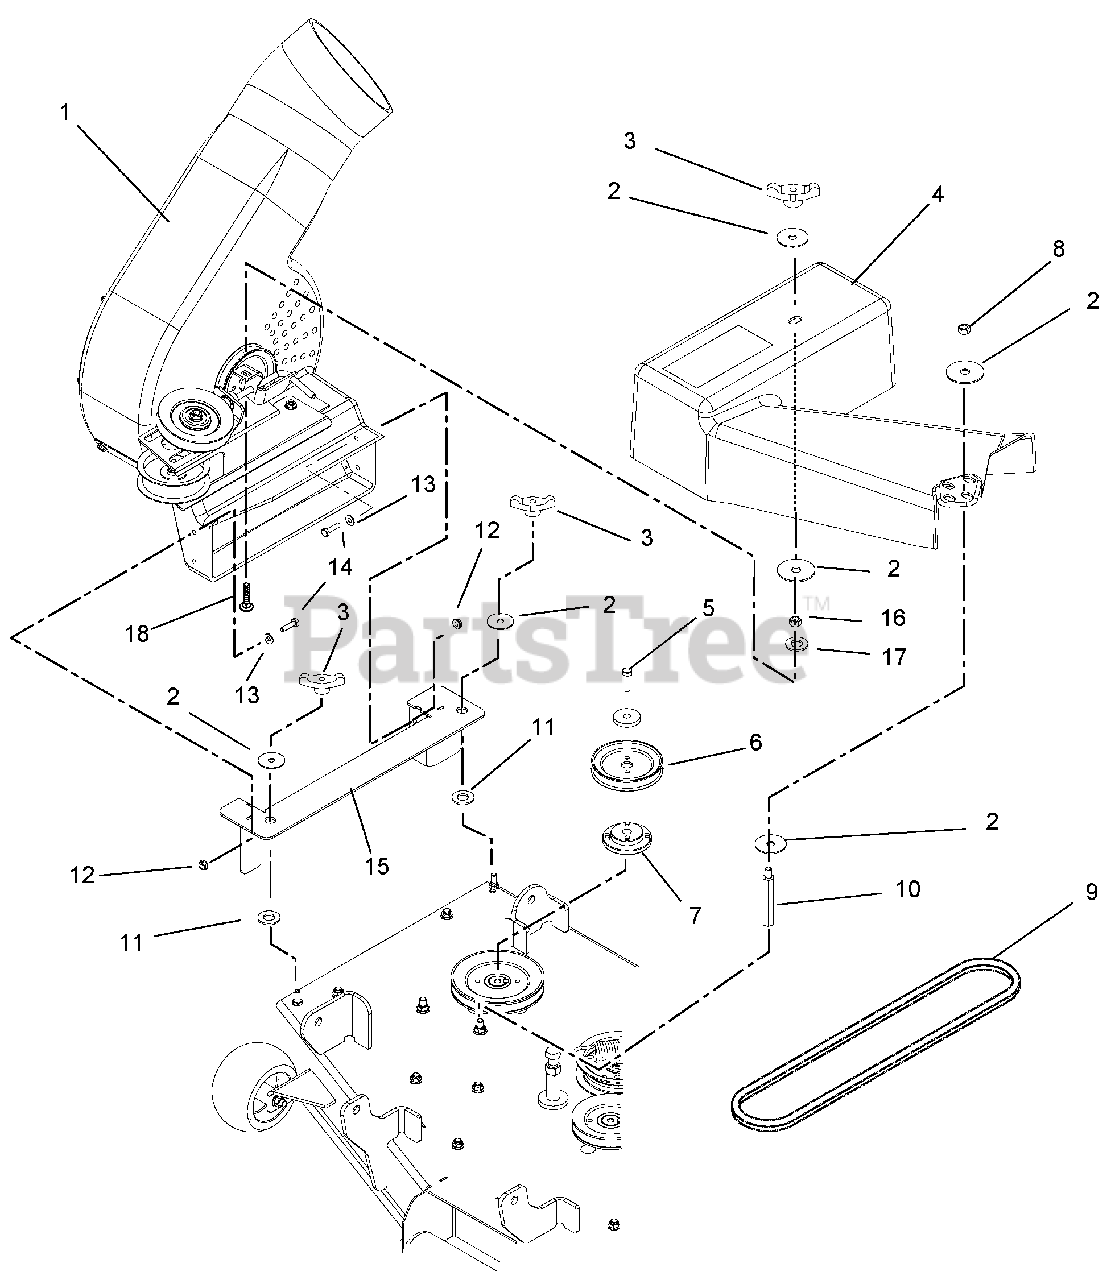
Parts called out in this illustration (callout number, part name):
1	BLOWER (SERVICE ASSEMBLY)
2	WSHR-FL-STL .380X1.50X.062 YWZ
3	KNOB - WING .312-18 UNC
4	BELT COVER, 34" ZTXL
5	BLT-HEX .38-16X1.75 GR8 M-EPYZ
6	SHEAVE, 4.00 DIA.
7	ASSEMBLY, SHEAVE ADAPTER
8	@NUT-LK-CTR .31-18 YWZC
9	V-BELT, HA-WRAPPED
10	STANDOFF, 2.75 X 5/16-18
11	WSHR-FL-STL .656X1.250X.10 YZC
12	@NUT-LK-NYL-FLG .25-20 YWZC
13	@WSHR-FL-STL.281X.62X.065 YWZC
14	@BLT-HEX .25-20X1.00 GR5 YWZC
15	WMT, BLOWER BRACKET
16	NUT- JAM .312-18 YWZC
17	@WSHR-FL-STL.312X.734X.065 YWZ
18	@BLT-RDHDSQNK .31-18X1.50 G5YZ
